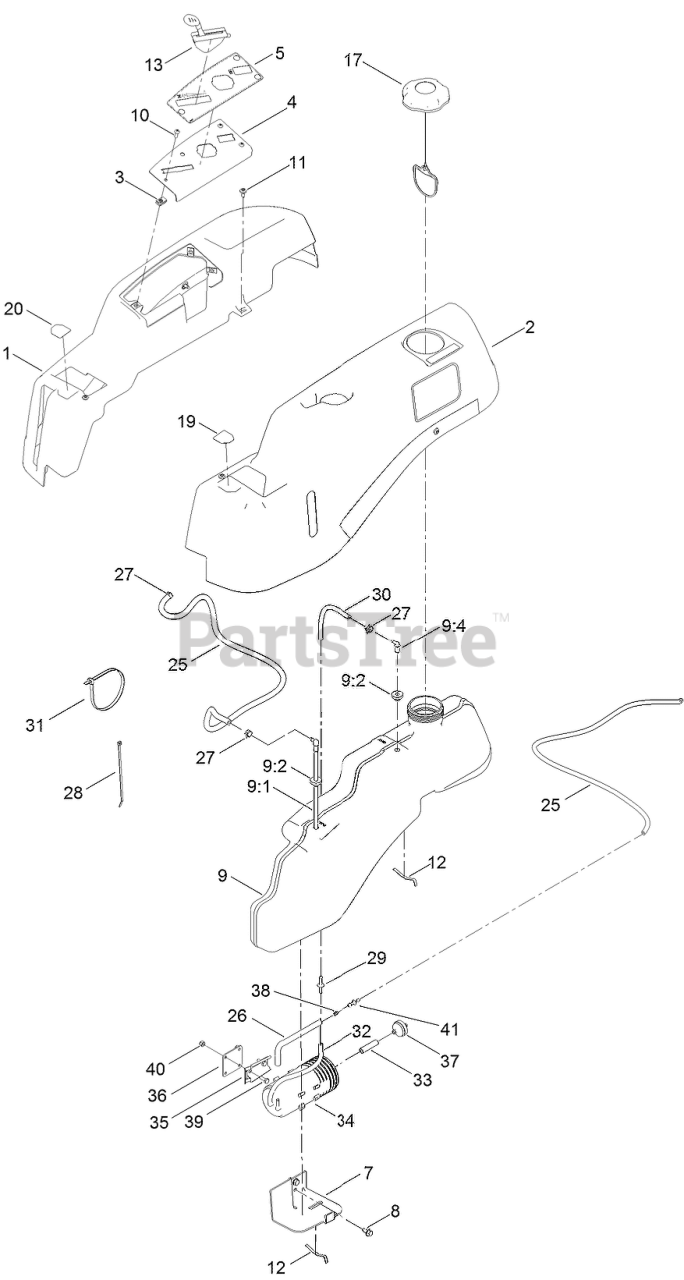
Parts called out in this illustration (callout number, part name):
1	POD-RH
4	PLATE-CONTROL
5	DECAL-PANEL, CONTROL
7	SUPPORT-TANK, FRONT
8	SCREW-HWHTF
9	FUEL TANK ASM
9:1	CONNECTOR-ELBOW, 90 DEG
9:2	BUSHING
9:4	FITTING-PLASTIC
10	SCREW-PRH
11	SCREW-SHOULDER
12	SPRING
13	CABLE-THROTTLE AND CHOKE
17	CAP-FUEL, RATCHETING
19	DECAL-LEVER, CONTROL (LH)
20	DECAL-LEVER, CONTROL (RH)
25	HOSE-FUEL
26	HOSE-FUEL
27	CLAMP-HOSE
28	TIE-CABLE
29	ADAPTOR-ORIFICE
30	HOSE-FUEL
31	TIE-CABLE
32	HOSE-FUEL
33	HOSE-FUEL
34	CANISTER-CARBON, 800CC
35	BRACKET-CANISTER, CARBON
36	PLATE-ADAPTER
37	FILTER-FUEL, INLINE
38	CARTRIDGE-VALVE, CHECK
39	SCREW-HH
40	NUT-LOCK, NI
41	FITTING-STRAIGHT
